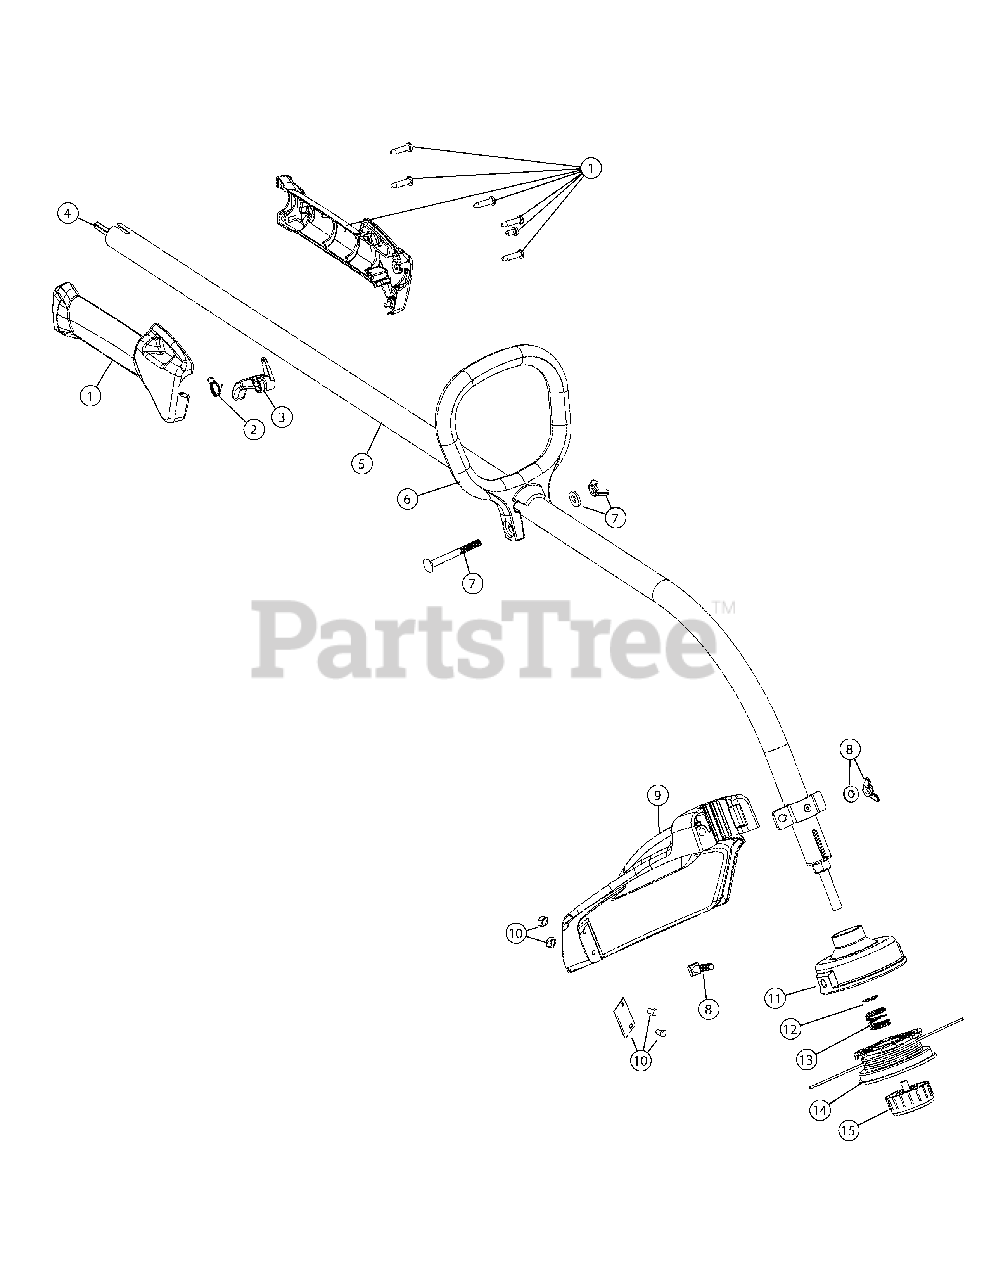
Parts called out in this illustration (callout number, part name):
1	Throttle Housing Assembly
2	Throttle Trigger Spring
3	Throttle Trigger
4	Flexible Drive Shaft
5	Drive Shaft Housing
6	D-Handle Assembly
7	D-Handle Hardware
8	Guard Mounting Hardware
9	Guard
10	Blade Assembly
11	Outer Reel
12	Retainer
14	Inner Reel
15	Bump Knob
